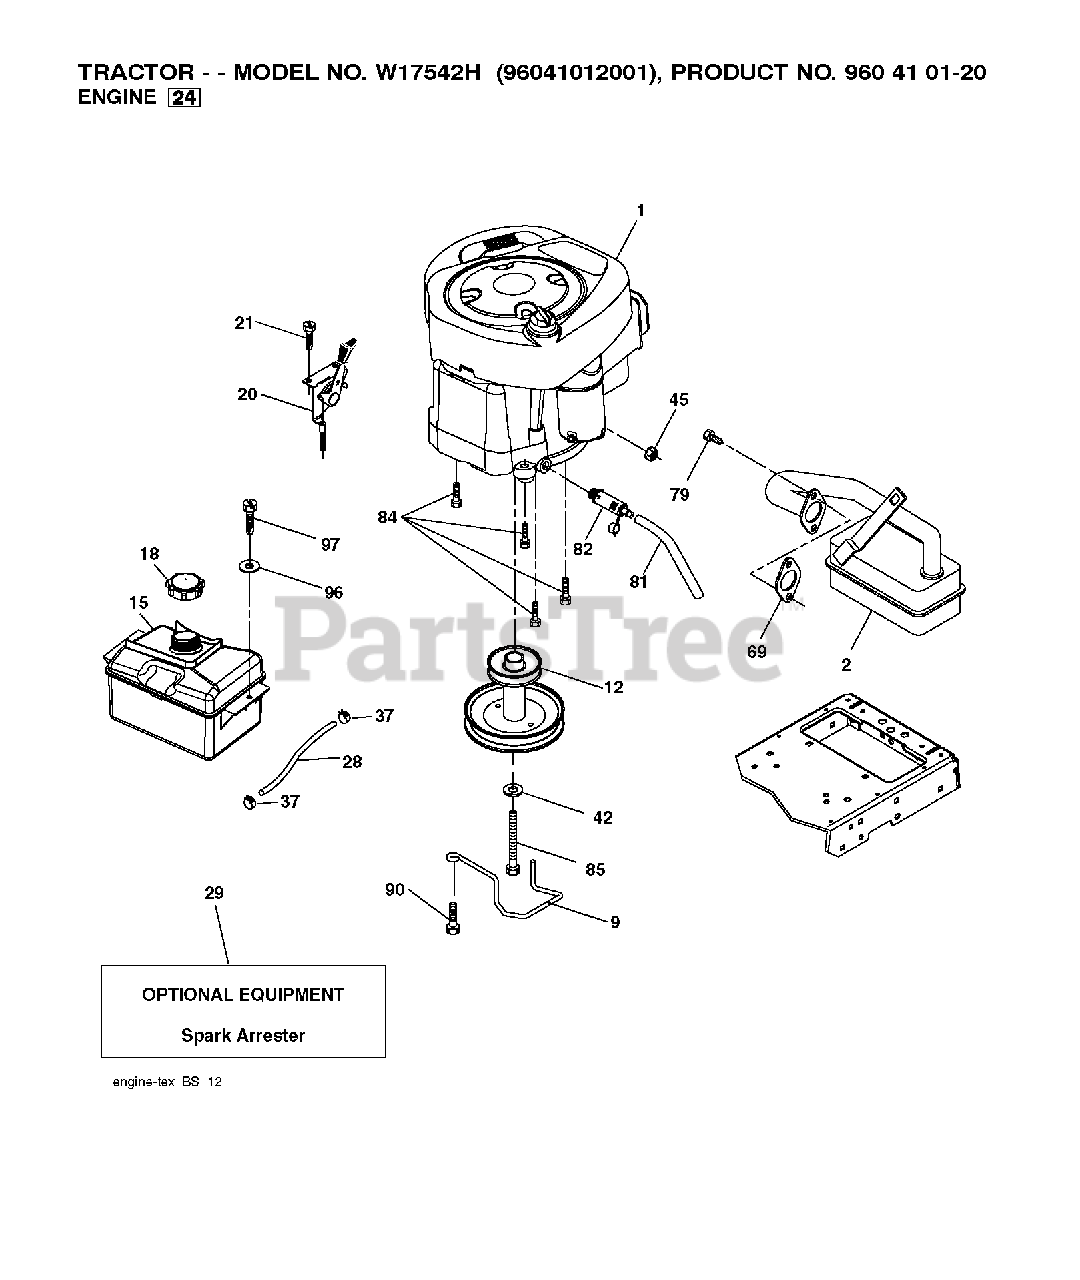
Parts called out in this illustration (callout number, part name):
1	Poulan TBD
2	MUFFLER.LT.BRIGGS.14HP.IC/OHV
9	KEEPER.BELT.ENGINE.4.2
12	PULLY ENGINE
15	RP TANK FUEL FRT 1.5 GAL
18	FUEL CAP
21	SCREW.#10 X 0.750.BOS (2 2)
28	LINE.FUEL.20
29	KIT.SPARK ARRESTOR(392390 B&S)
37	HOSE CLAMP
42	LOCKWASHER
45	NUT
79	SCREW.SOCKET HD.5/16-1
81	TUBE, DRAIN OIL ASM.
82	PLUG DRAIN OIL EASY
84	SCREW.3/8-16
85	BOLT HEX 7/16-20X4-1/4"
90	SCREW 3/8-16X1
97	SCREW HEXWSHR 1/4-20X3/4
